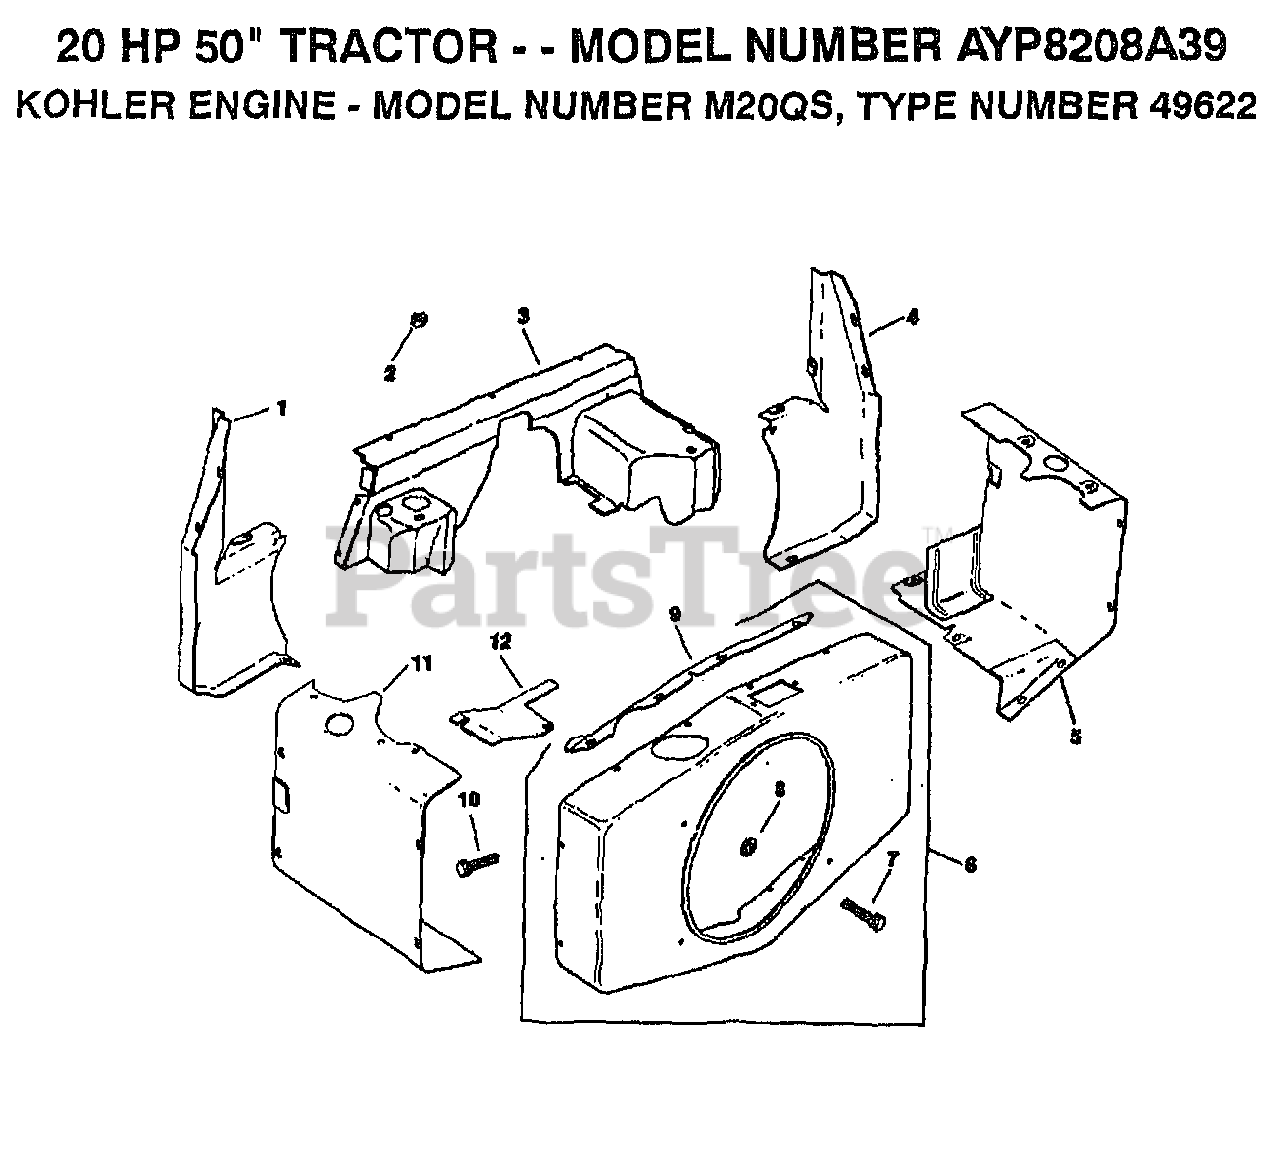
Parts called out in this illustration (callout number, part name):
1	DUCT, AIR, #1 SIDE
3	COVER, AIR DUCT
4	DUCT, AIR, #2 SIDE
5	BAFFLE, #1 CYLINDER HEAD
6	KIT, BLOWER HOUSING
9	SUPPORT, UPPER HOUSING
11	BAFFLE, #2 CYLINDER HEAD
12	BAFFLE, #2 CYLINDER TOP
